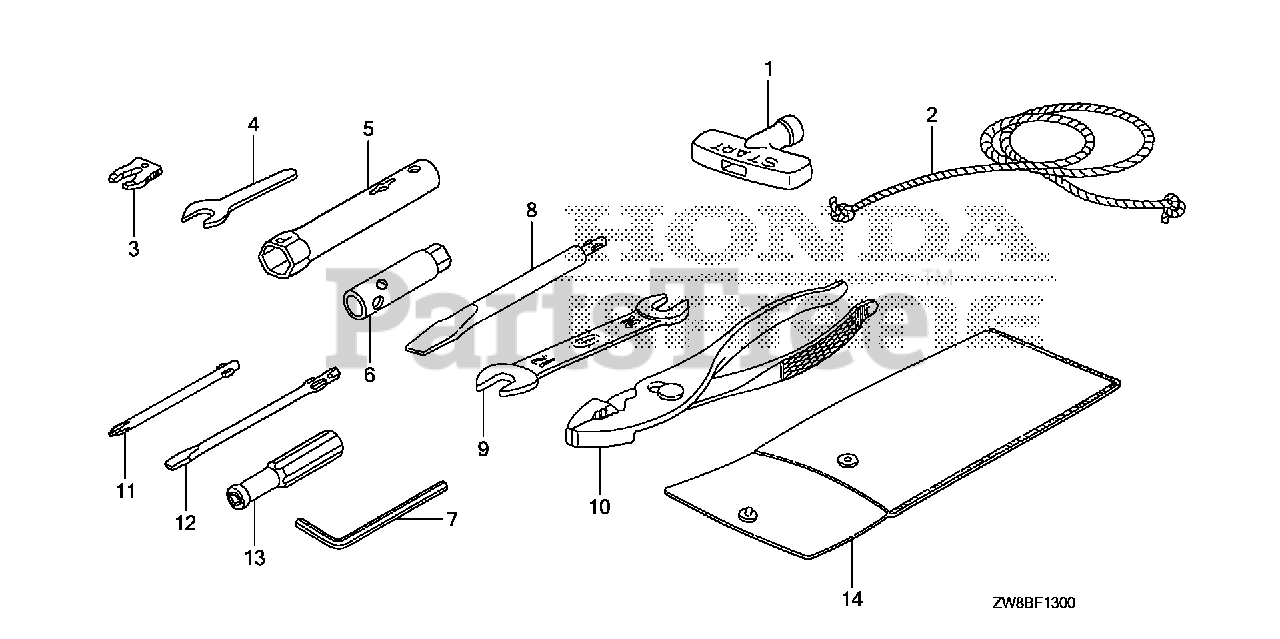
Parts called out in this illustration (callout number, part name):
1	GRIP, STARTER
2	ROPE, RECOIL STARTER (1300MM)
3	CLIP, EMERGENCY LOCK
4	WRENCH (8MM) (OPEN END) (NOT AVAILABLE)
5	WRENCH, SPARK PLUG
6	WRENCH, BOX (10MM) (NOT AVAILABLE)
7	WRENCH, HEX. (4MM)
8	SCREWDRIVER, CHECK BOLT
9	WRENCH (10X12) (OPEN END)
10	PLIERS (135) (RIKEN)
11	SCREWDRIVER 1, PHILLIPS (NO.2)
12	SCREWDRIVER 3, STRAIGHT SLOT (NO. 2)
13	GRIP, SCREW DRIVER
14	BAG, TOOL (160MM)
